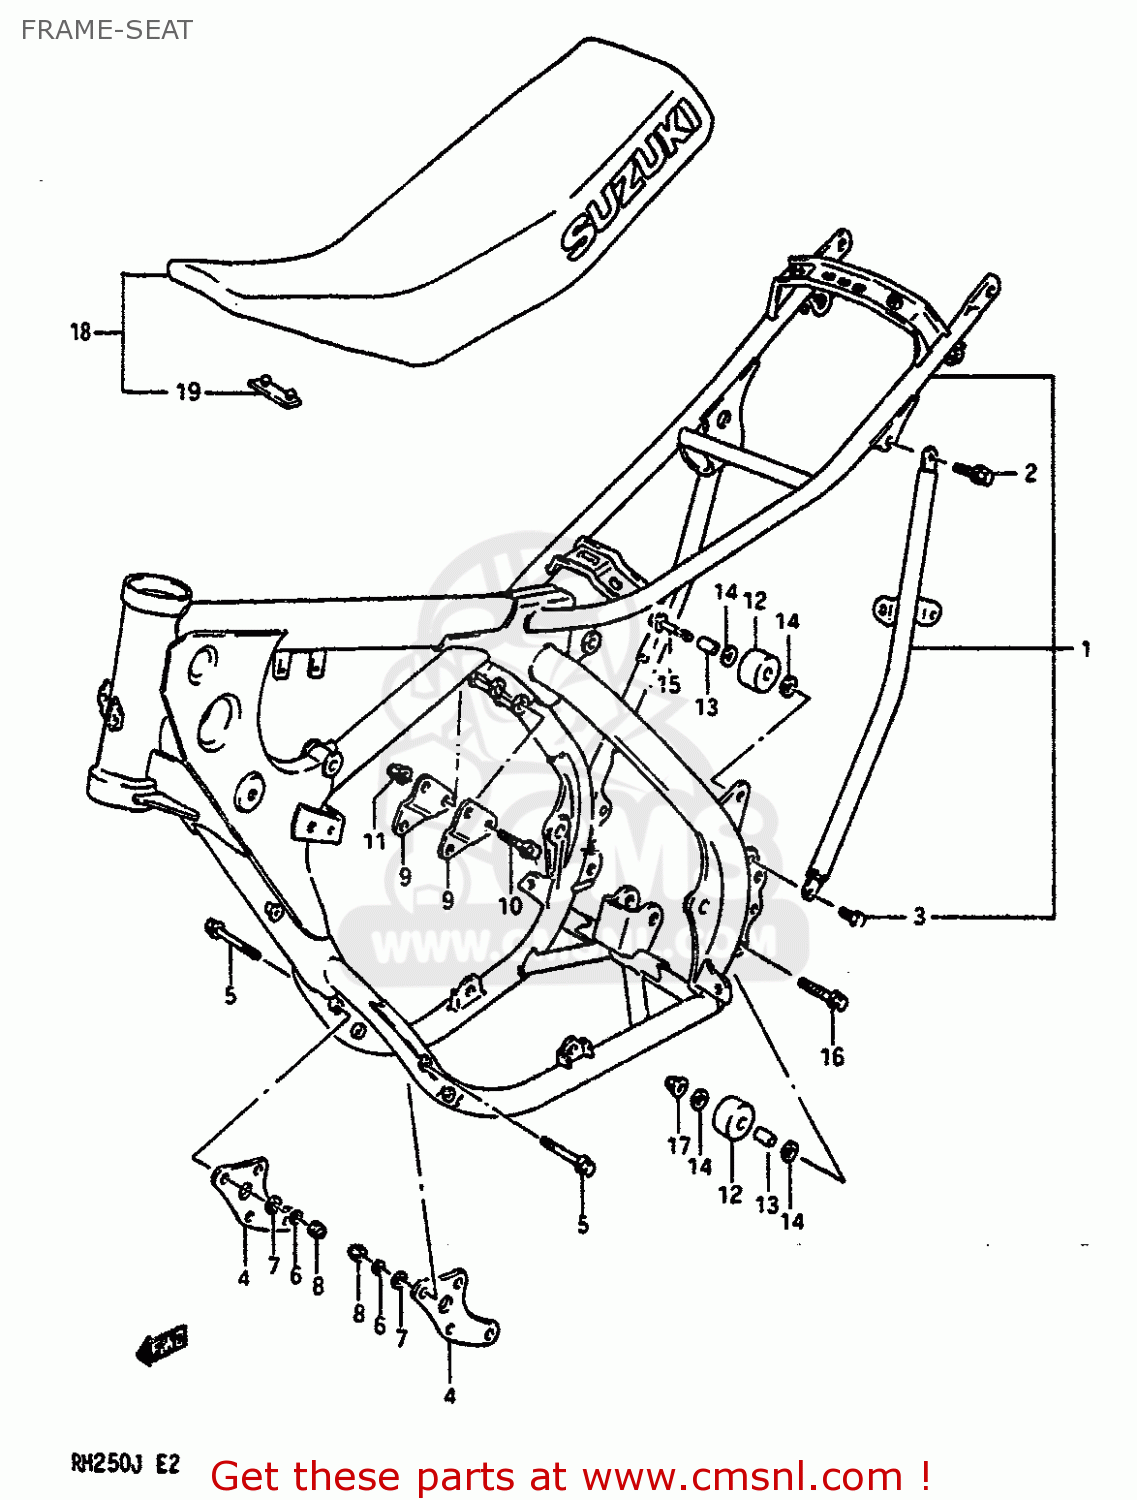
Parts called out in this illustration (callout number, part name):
1	FRAME
2	BOLT
3	BOLT
4	PLATE,ENGINE MOUNTING
5	BOLT 8X55
6	LOCK WASHER
7	WASHER
8	NUT
9	PLATE,ENGINE MOUNTING
10	BOLT 8X45
11	NUT
12	ROLLER,CHAIN CONTROL
13	SPACER (8.6X13.8X28)
14	WASHER
15	BOLT(8X41)
16	BOLT(8X50)
17	NUT
18	SEAT SET
19	CUSHION
